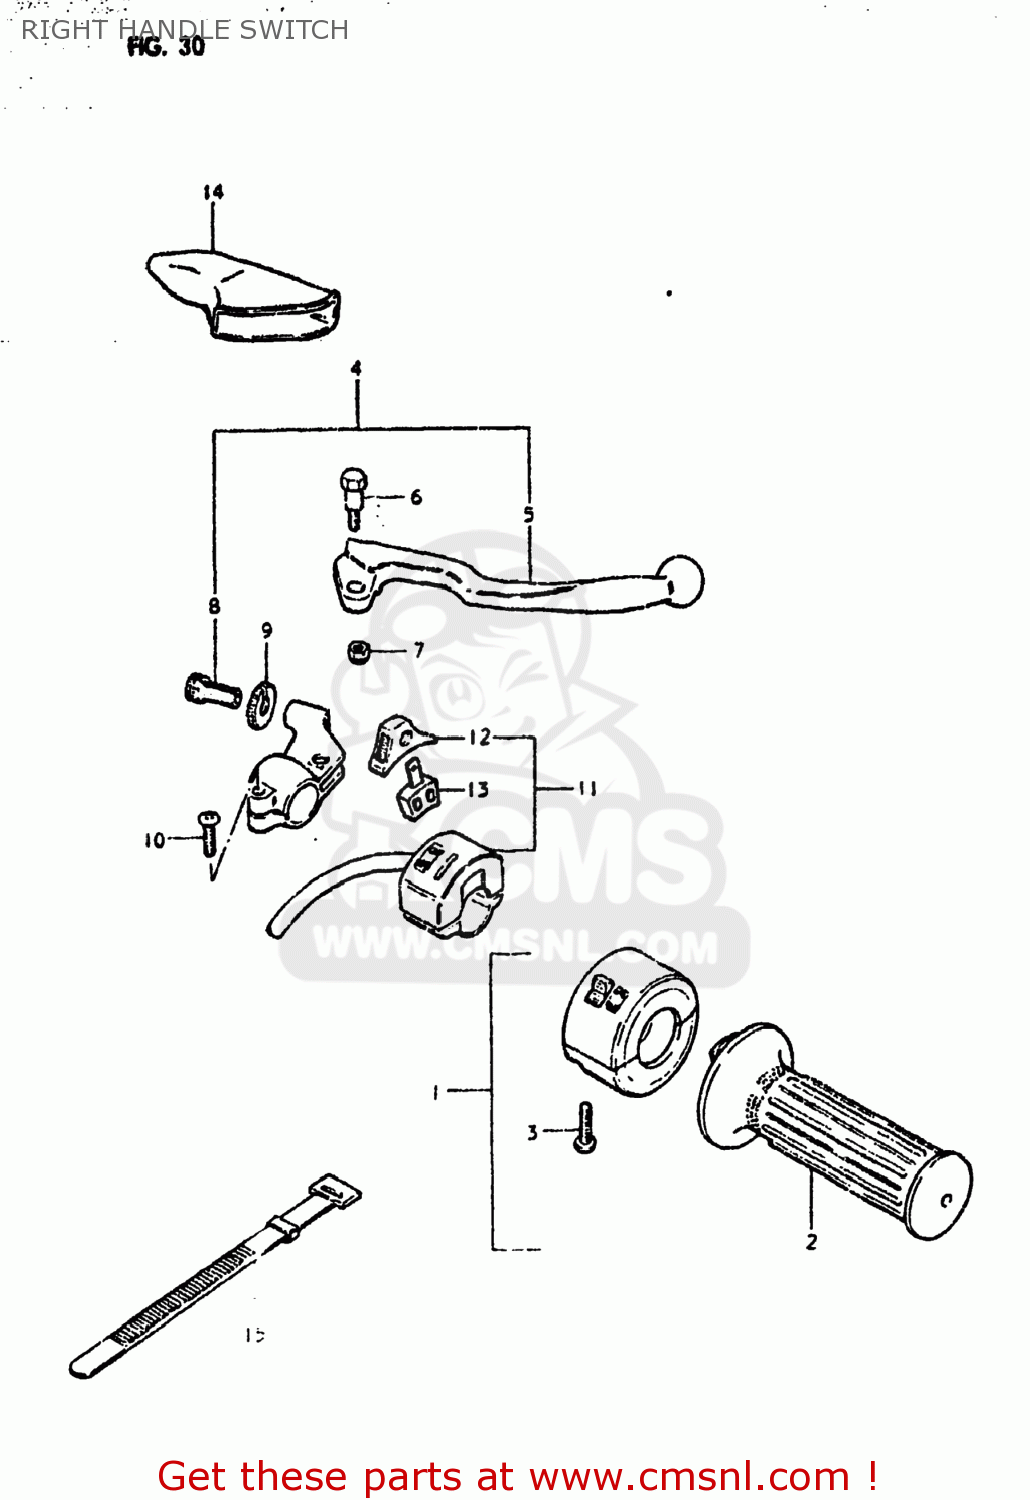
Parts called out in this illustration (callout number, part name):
1	CASE ASSEMBLY,THROTTLE
2	GRIP,THROTTLE
3	SCREW
4	LEVER ASSEMBLY,BRAKE
5	LEVER,BRAKE
6	BOLT,LEVER
7	NUT 6MM
8	ADJUSTER,CABLE
9	NUT,CABLE ADJUSTER
10	SCREW
11	SWITCH ASSEMBLY,LIGHTING
12	KNOB,LIGHTING & DIMMER
13	BLOCK,LIGHTING/DIMMER
14	COVER,CLUTCH LEVER
15	CLAMP(L:120)
